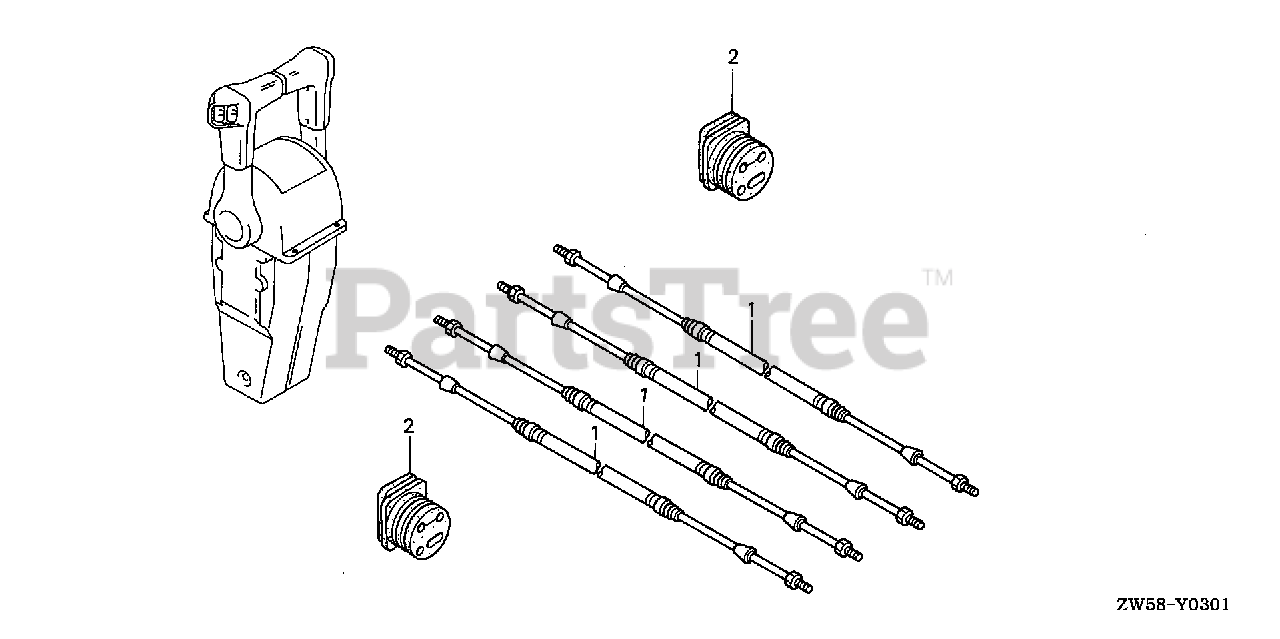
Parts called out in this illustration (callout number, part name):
1	CABLE, REMOTE CONTROL (10') (LOW FRICTION)
1	CABLE ASSY., PUSH-PULL (33C-5FT)
1	CABLE, REMOTE CONTROL (11') (LOW FRICTION)
1	CABLE ASSY., PUSH-PULL (33C-6FT)
1	CABLE, REMOTE CONTROL (12') (LOW FRICTION)
1	CABLE ASSY., PUSH-PULL (33C-7FT)
1	CABLE, REMOTE CONTROL (13') (LOW FRICTION)
1	CABLE ASSY., PUSH-PULL (33C-8FT)
1	CABLE, REMOTE CONTROL (14') (LOW FRICTION)
1	CABLE ASSY., PUSH-PULL (33C-9FT)
1	CABLE, REMOTE CONTROL (15') (LOW FRICTION)
1	CABLE ASSY., PUSH-PULL (33C-10FT)
1	CABLE, REMOTE CONTROL (16') (LOW FRICTION) (NOT AVAILABLE)
1	CABLE ASSY., PUSH-PULL (33C-11FT)
1	CABLE, REMOTE CONTROL (17') (LOW FRICTION)
1	CABLE ASSY., PUSH-PULL (33C-12FT)
1	CABLE, REMOTE CONTROL (18') (LOW FRICTION) (NOT AVAILABLE)
1	CABLE ASSY., PUSH-PULL (33C-13FT)
1	CABLE, REMOTE CONTROL (19') (LOW FRICTION)
1	CABLE ASSY., PUSH-PULL (33C-14FT)
1	CABLE, REMOTE CONTROL (20') (LOW FRICTION) (NOT AVAILABLE)
1	CABLE ASSY., PUSH-PULL (33C-15FT)
1	CABLE, REMOTE CONTROL (21') (LOW FRICTION)
1	CABLE ASSY., PUSH-PULL (33C-16FT)
1	CABLE, REMOTE CONTROL (22') (LOW FRICTION) (NOT AVAILABLE)
1	CABLE ASSY., PUSH-PULL (33C-17FT)
1	CABLE, REMOTE CONTROL (23') (LOW FRICTION)
1	CABLE ASSY., PUSH-PULL (33C-18FT)
1	CABLE, REMOTE CONTROL (24') (LOW FRICTION) (NOT AVAILABLE)
1	CABLE ASSY., PUSH-PULL (33C-19FT)
1	CABLE, REMOTE CONTROL (25') (LOW FRICTION)
1	CABLE ASSY., PUSH-PULL (33C-20FT)
1	CABLE, REMOTE CONTROL (26') (LOW FRICTION)
1	CABLE ASSY., PUSH-PULL (33C-21FT)
1	CABLE, REMOTE CONTROL (27') (LOW FRICTION)
1	CABLE ASSY., PUSH-PULL (33C-22FT)
1	CABLE, REMOTE CONTROL (28') (LOW FRICTION) (NOT AVAILABLE)
1	CABLE ASSY., PUSH-PULL (33C-23FT)
1	CABLE, REMOTE CONTROL (29') (LOW FRICTION)
1	CABLE ASSY., PUSH-PULL (33C-24FT)
1	CABLE, REMOTE CONTROL (30') (LOW FRICTION) (NOT AVAILABLE)
1	CABLE ASSY., PUSH-PULL (33C-25FT)
1	CABLE, REMOTE CONTROL (31') (LOW FRICTION)
1	CABLE ASSY., PUSH-PULL (33C-26FT)
1	CABLE, REMOTE CONTROL (32') (LOW FRICTION) (NOT AVAILABLE)
1	CABLE ASSY., PUSH-PULL (33C-27FT)
1	CABLE, REMOTE CONTROL (33') (LOW FRICTION)
1	CABLE ASSY., PUSH-PULL (33C-28FT)
1	CABLE, REMOTE CONTROL (34') (LOW FRICTION) (NOT AVAILABLE)
1	CABLE ASSY., PUSH-PULL (33C-29FT)
1	CABLE, REMOTE CONTROL (35') (LOW FRICTION)
1	CABLE ASSY., PUSH-PULL (33C-30FT)
1	CABLE ASSY., PUSH-PULL (33C-31FT)
1	CABLE ASSY., PUSH-PULL (33C-32FT)
2	GROMMET, CASE (LOWER) (B)
